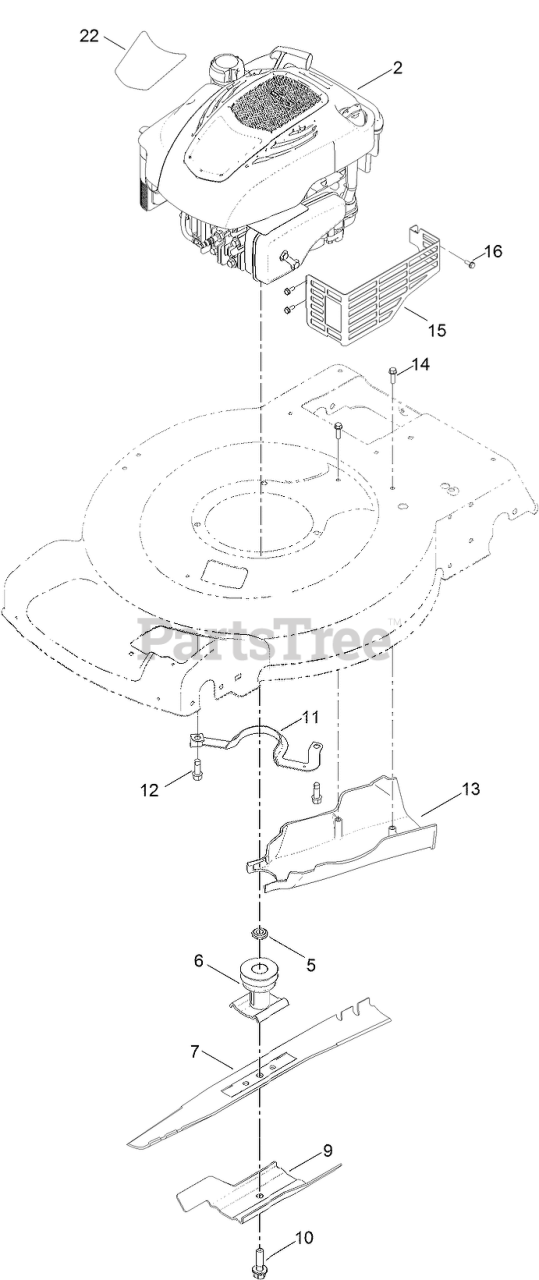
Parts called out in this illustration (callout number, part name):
5	Spacer-Driver
6	DRIVER-BLADE
7	BLADE
9	Accelerator-Blade
10	BOLT-BLADE
11	GUIDE-BELT
12	SCREW-TAPTITE
13	COVER-BELT, REAR
14	SCREW-HWH
15	SHIELD-MUFFLER
16	SCREW-TAPTITE
22	DECAL-SHROUD
